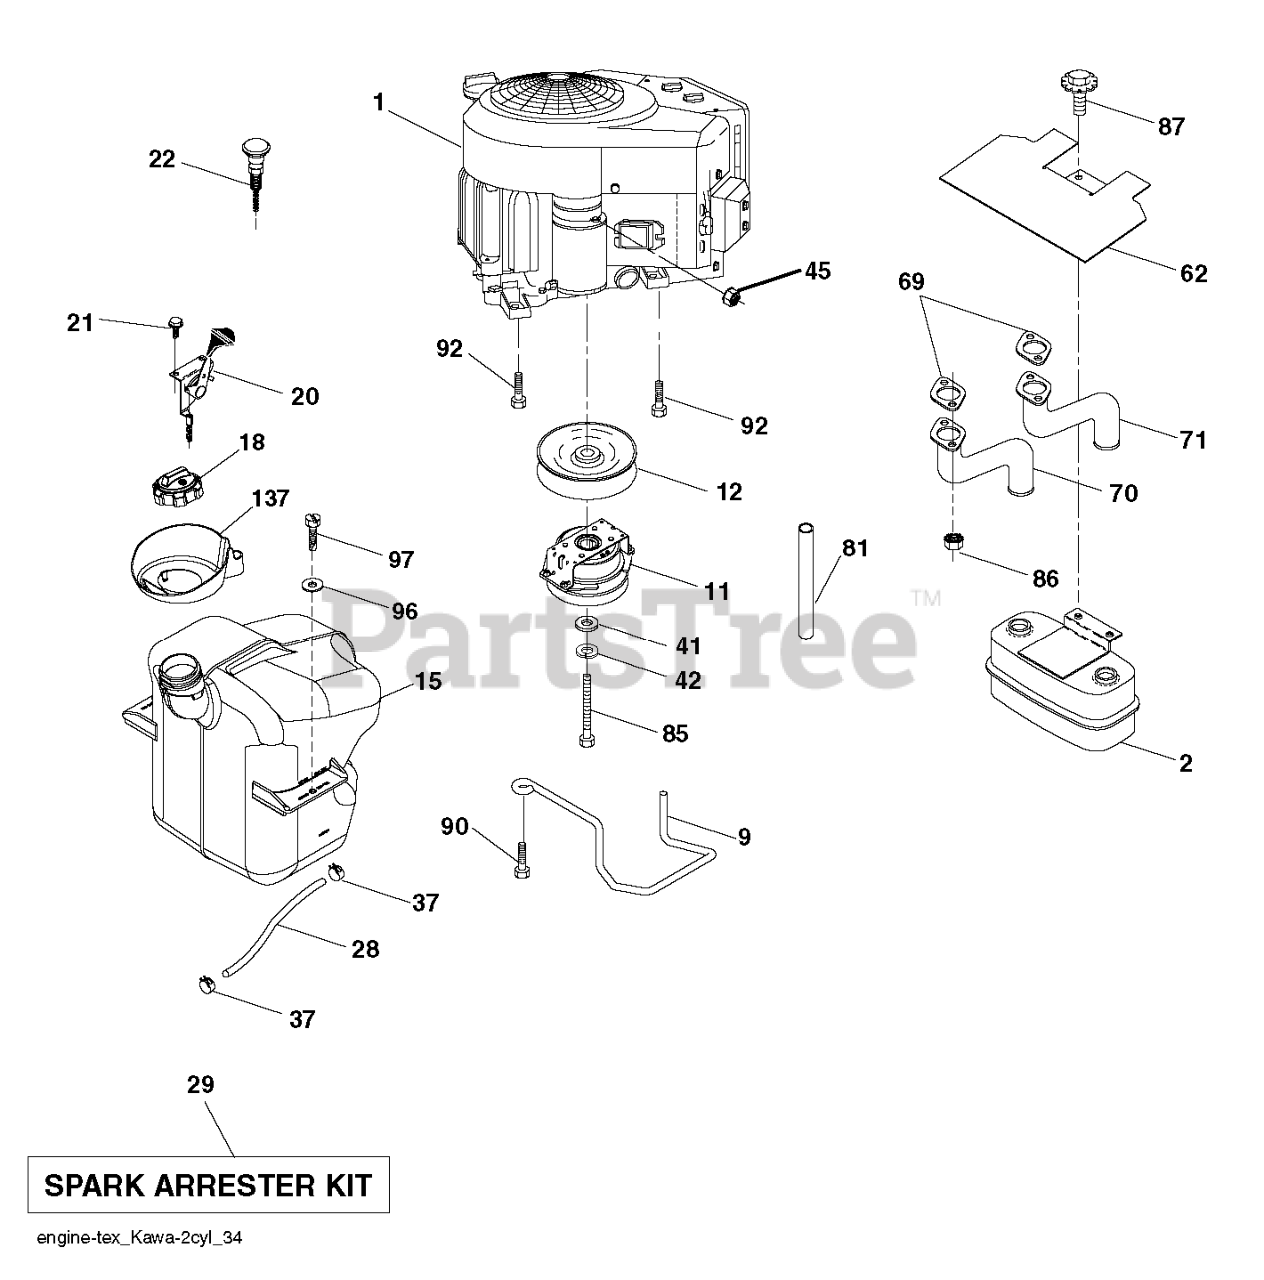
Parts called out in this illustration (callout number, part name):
2	MUFFLER.ASM.TWN.EXTNDED.DFLCTR
9	KEEPER.BELT.ENGINE.4.2
11	CLUTCH.ELECTRIC.LT.48"*
12	PULLEY.ENGINE.TUFFTORQ
15	FUEL TANK TANK. ASSEMBLY. EXTE
18	CAP.ASM.FUEL.2.25"TOP.TURN
20	CONTROL.THROTTLE.COBRA.BLACK
21	SCREW.#10 X 0.750.BOS
22	CONTROL, CHOKE
28	LINE.FUEL.20
29	KIT.SPARK ARRESTOR 794945 B&S
37	HOSE CLAMP
42	LOCKWASHER
45	NUT
62	SHIELD.HEAT.MUFFLER
70	TUBE.EXHAUST.LH.FR961/FR730
71	TUBE.EXHAUST.RH.FR961/FR730
81	TUBE, DRAIN OIL ASM.
85	BOLT HEX 7/16-20X4-1/4"
86	NUT.HEX.FLANGE.TOPLOCK
87	BOLT.5/16-18UNCX3/4 W/SEMS.BLK
90	SCREW 3/8-16X1
92	SCREW 3/8-16X1
96	WASHER
97	SCREW HEXWSHR 1/4-20X3/4
